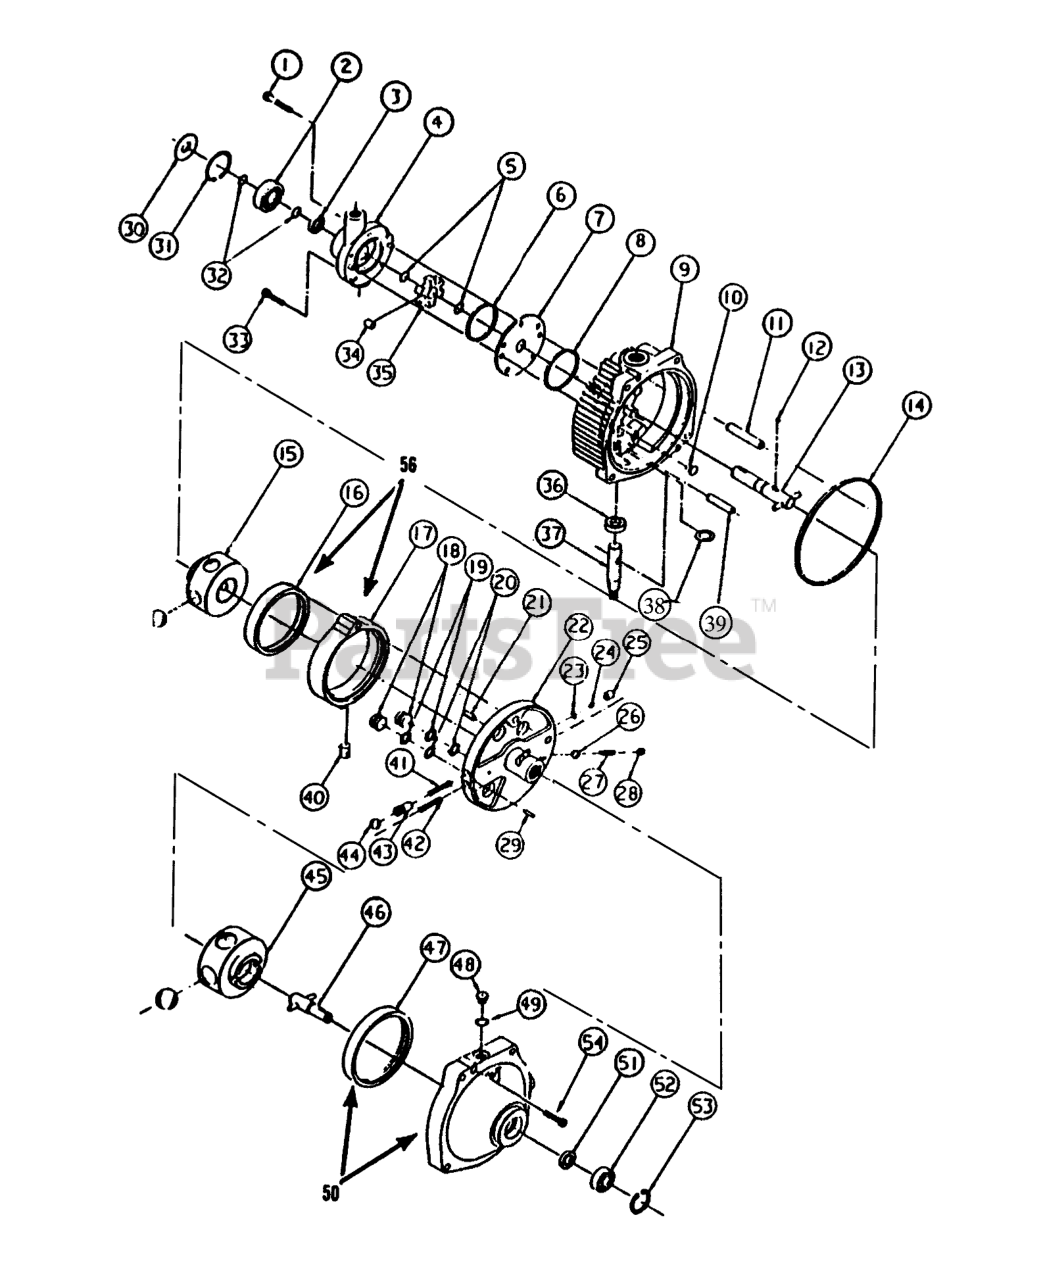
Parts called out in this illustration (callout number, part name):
1	Screw
2	Bearing-Input
3	Seal
4	Housing-Pump Assembly (Incl.Ref.# 2)
5	Ring
6	Ring-Seal
7	Plate
8	Ring-Seal
9	Cover Assembly(Incl. Ref.#3,6,8,10,11,19,20,36-39,&51)
10	Button
11	Pin-Pivot
12	Pin
13	Shaft-Input
14	Ring-Seal
15	Rotor-Pump
16	PUMP-RACE
17	Ring-Cam
18	Piston
19	Ring-Back Up
20	"O"Ring
21	Pin-Coil
22	Pintle Assembly(Inc. Ref.#21,23-29&41-44)
23	Ring-Retaining
24	Ball
25	Body-Check Valve
26	Ball
27	Spring-Relief Valve
28	Plug-Relief Valve
29	Pin
30	SHIELD-GRASS
31	RETAINING-RING
32	Ring
33	Screw
34	Roller
35	Carrier
36	Seal
37	Kit-Control
38	Washer
39	Dowel
40	Insert-Cam Ring
41	Spring-Acc. Valve
42	Spring-Acc. Valve
43	Body-Acc. Valve
44	Ball
45	Rotor-Motor
46	Shaft-Output
47	Race-Motor
48	Plug-"O"Ring (Incl. Ref. #49)
49	O-Ring
50	Body Assembly (Incl. Ref.#51,53&54)
51	Seal ASM
52	Bearing-Output
53	Retaining Ring
54	Screw
55	Kit-Seal, Overhaul (Incl. Ref. #3, 6, 8, 14, 19, 20, 36, 49 & 51)
56	Ring-Cam
